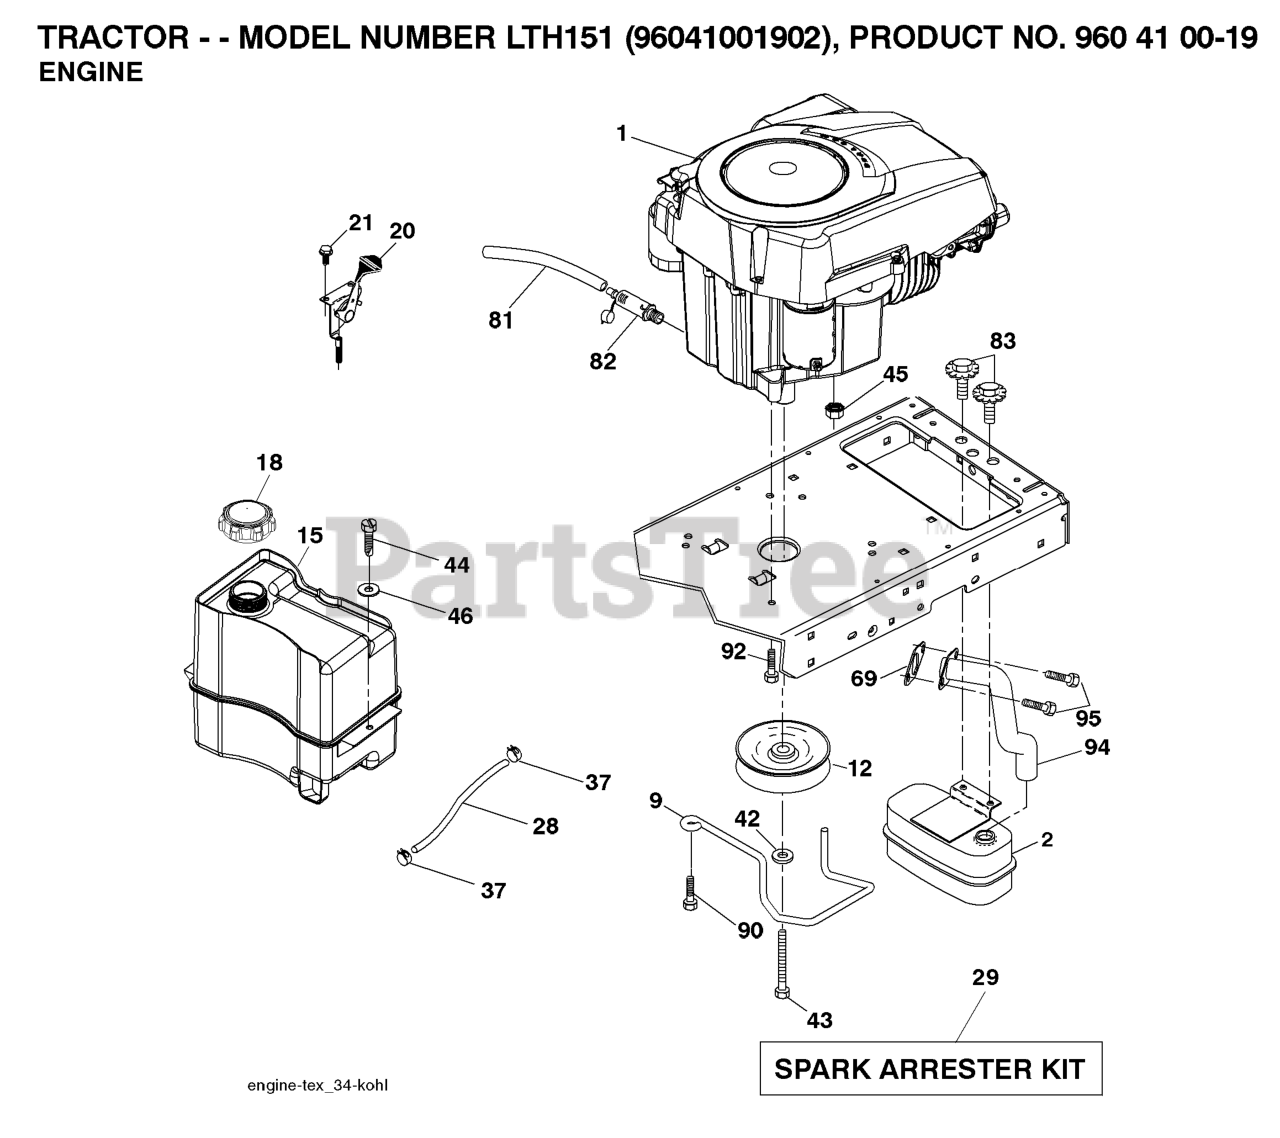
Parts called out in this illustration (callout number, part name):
2	MUFFLER.SINGLE.CYL.KOHL/B&S
9	KEEPER.BELT.ENGINE.4.2
12	PULLY ENGINE
15	RP TANK FUEL FRT 1.5 GAL
18	FUEL CAP
20	CONTROL.TH/CK.C.
21	SCREW
28	LINE.FUEL.20
29	KIT.SPARK ARRESTOR 794945 B&S
37	HOSE CLAMP
42	LOCKWASHER
43	BOLT HEX 7/16-20X4-1/4"
44	SCREW HEXWSHR 1/4-20X3/4
45	NUT
81	TUBE, DRAIN OIL ASM.
82	PLUG DRAIN OIL EASY
83	BOLT.5/16-18UNCX3/4 W/SEMS.BLK
90	SCREW 3/8-16X1
92	SCREW 3/8-16X1
94	RP.TUBE.EXHAUST.KOHL.COURAGE
95	SCREW.SOCKET HD.5/16-1
